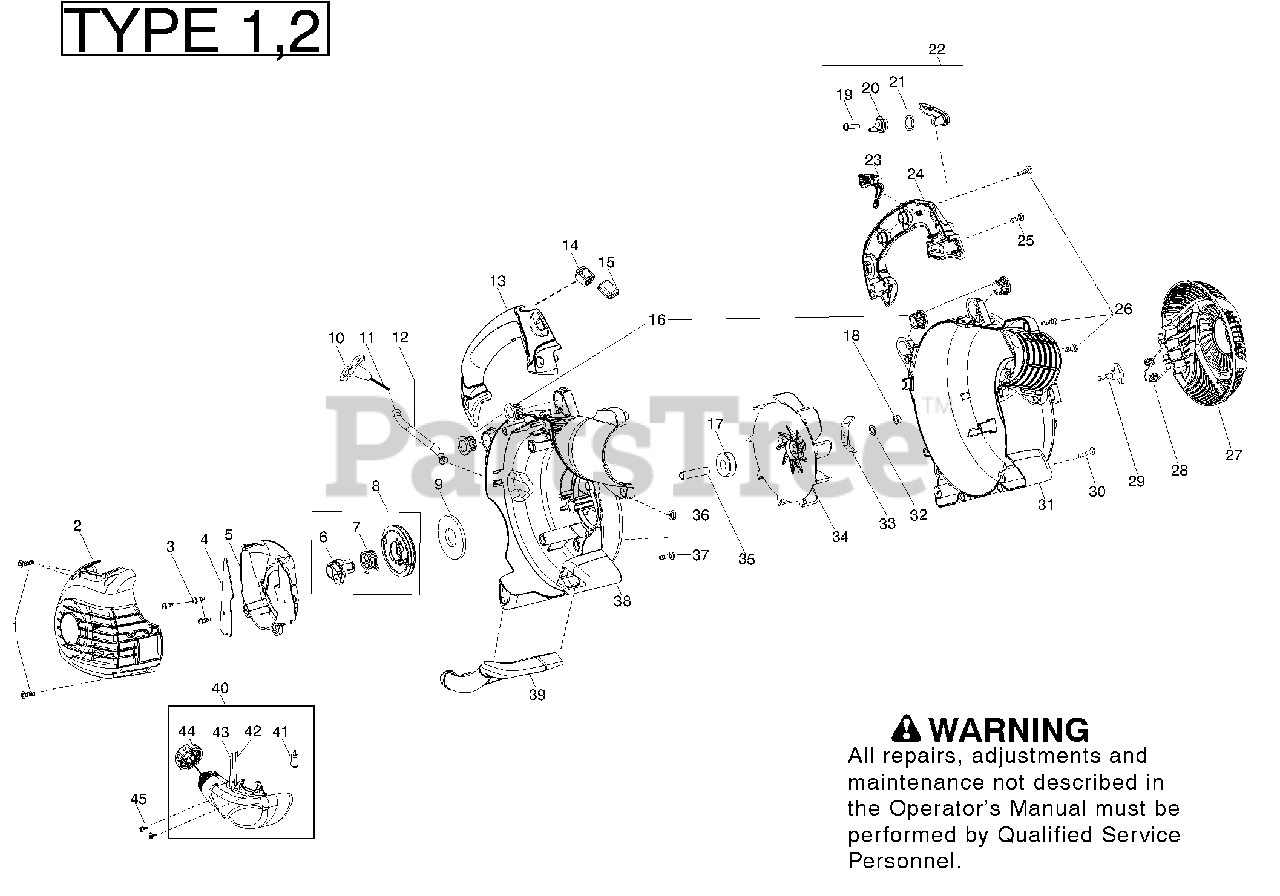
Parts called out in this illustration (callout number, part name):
2	Assy - Engine Cover
4	Shield - Baffle
7	Spring - Pulley
8	Kit - Starter Pulley
9	Spring -Starter
10	Handle - starter
11	Kit - Rope
12	Tube - Starter Rope
13	Handle - RH
14	Kit - Switch
15	Protector - Switch
20	Rachet - Cruise Control
21	Washer - Wave
22	Kit - Cruise Control
23	Trigger - Throttle
24	Handle - LH
27	Door -Vac
28	Spring - Vac Door
29	Knob - Blower
30	Screw - Vac Handle
31	Assy - Scroll LH
32	Washer - Lock
33	Blade - Mulch
34	Assy - Impeller
35	Spacer - Flywheel
36	Nut - Blower Knob
38	Assy - Scroll RH
39	Handle - Vac
40	Assy - Fuel Tank
41	Assy - Fuel Pickup
42	Kit - Fuel Line (carb/purge)
43	Kit - Fuel Line (tank/purge)
44	Assy - Fuel Cap w/retainer
45	Screw - Fuel Tank Retainer
